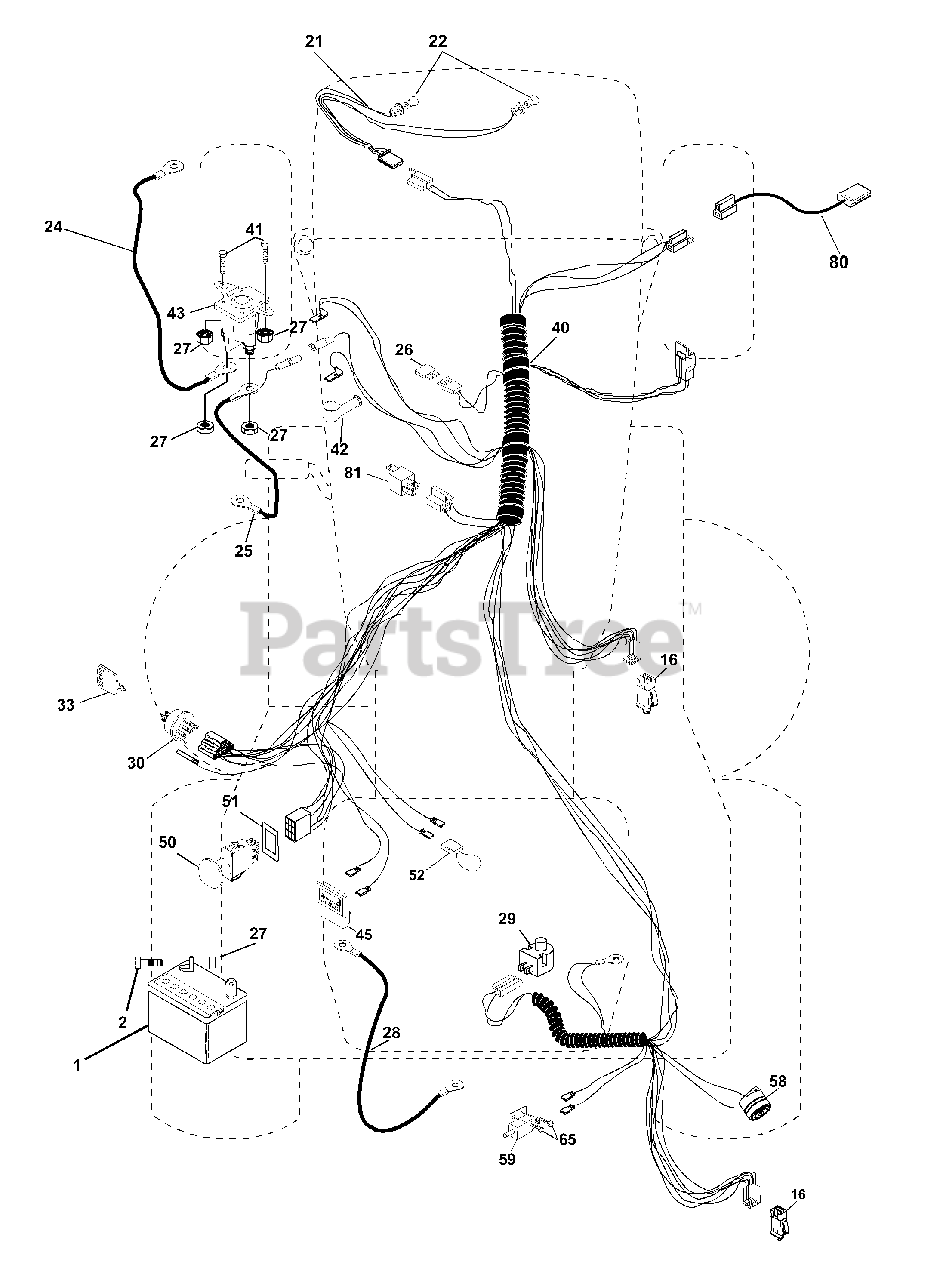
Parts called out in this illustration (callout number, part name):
1	Battery 12 Volt 25 Amp
2	Bolt Hex Hd 1/4-20unc X 3/4
16	Switch Interlock
21	Harness Asm Light W/4152J
22	Bulb Light #1156
24	Cable Starter 6 Ga 11" Red
25	Cable Battery CRD 56" Red
26	Fuse 15 Amp
27	Nut Keps Hex 1/4-20 Unc
28	Cable Ground
29	Switch Plunger OP Olive
30	Switch Ign
40	Harness Ign
41	Bolt Blk Fin Hex 1/4-20 Unc x 1/2
42	Cover Terminal Red
43	Solenoid
45	Ammeter Rectangular 15 Amp
50	Switch PTO 3PDT Black Delta
51	Ring Retainer PTO
53	Protection Wire Loop
58	Buzzer CRD
59	Switch FBI CRD
65	Screw Slfts #10-16 x 1/2
66	Screw Thdrol 3/8-16 x 1/2
80	Harness Clutch Evx
81	Relay Asm.
